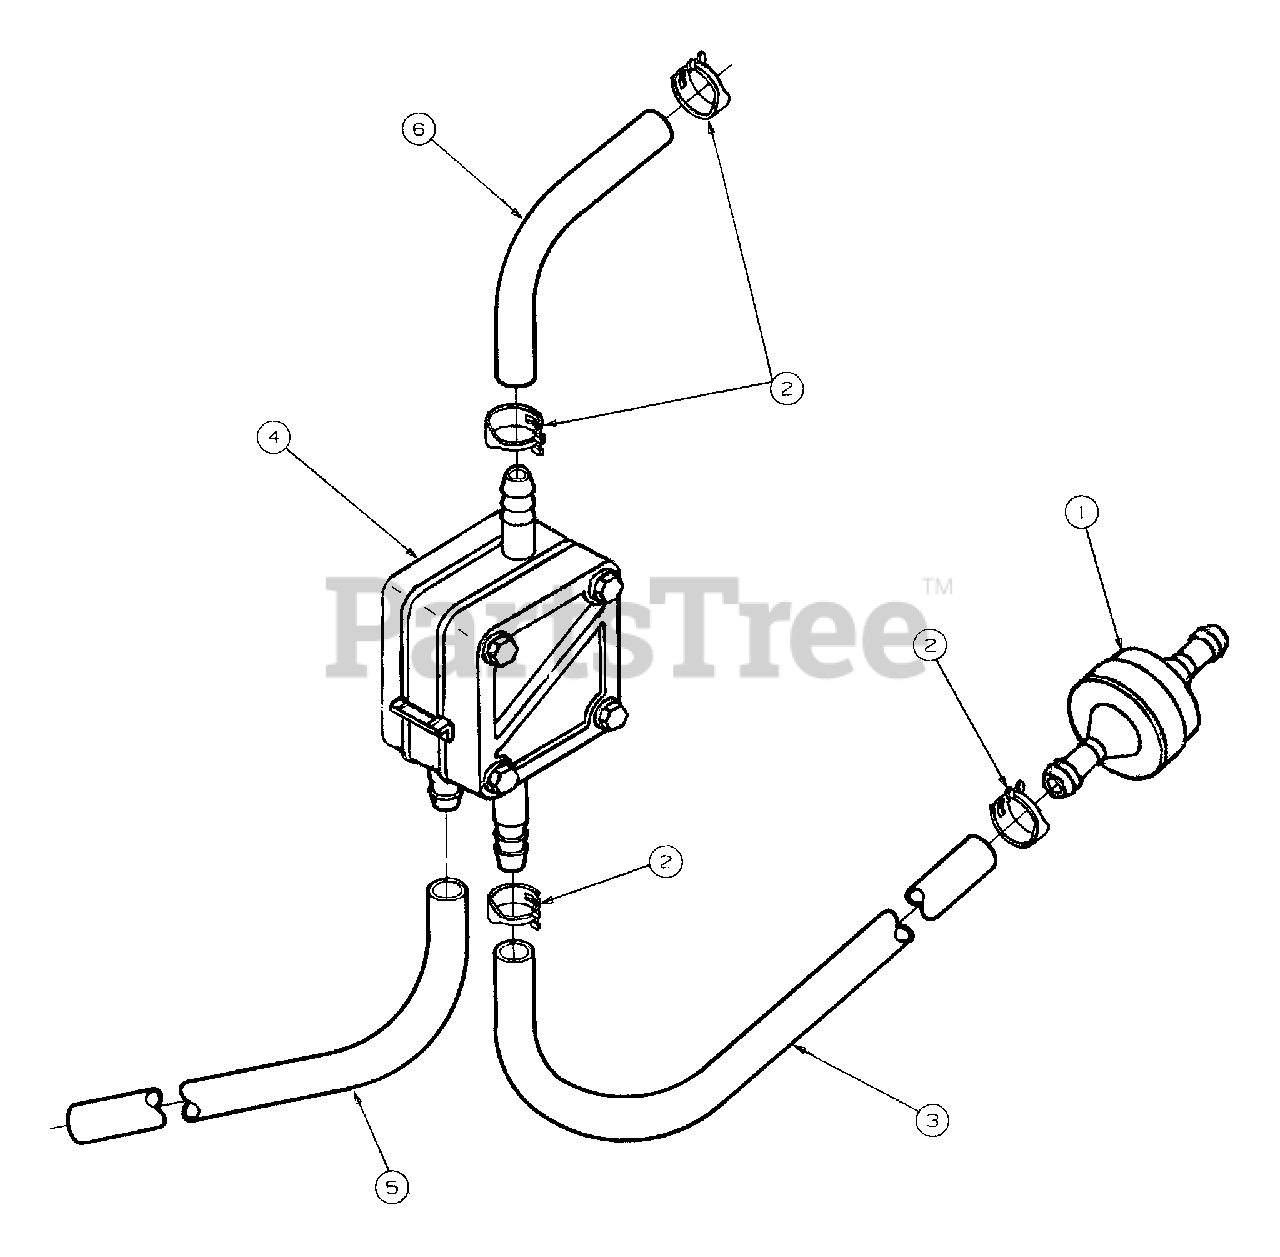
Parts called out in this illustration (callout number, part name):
1	Filter, Fuel
2	Clamp, Hose
3	Hose, Bulk Fuel (1/4 x 230mm)
5	Hose, Bulk Fuel, Pulse Line, 1/4 x 116mm
6	Hose, Bulk Fuel, Outlet, 1/4 x 54mm
